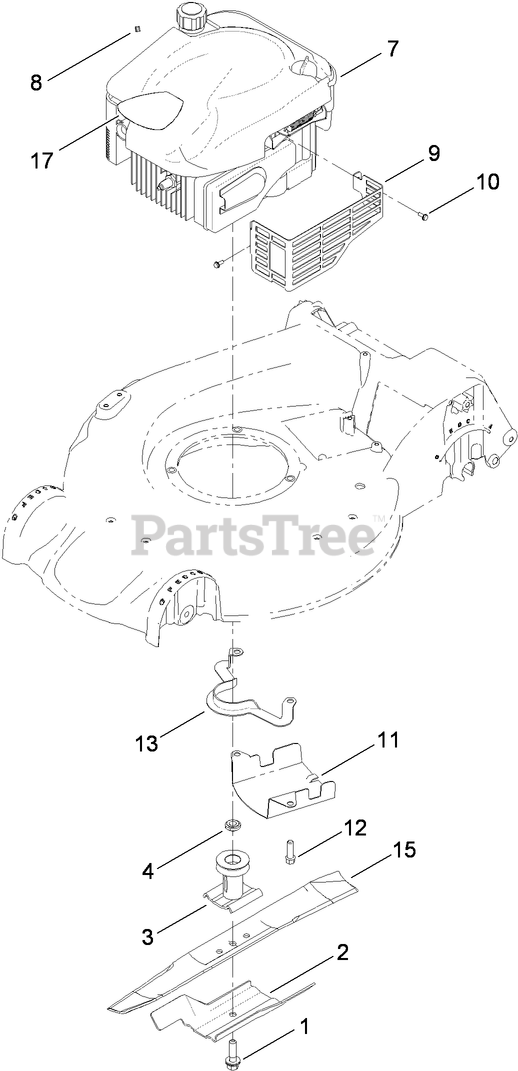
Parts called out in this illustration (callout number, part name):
2	ACCELERATOR-BLADE
3	DRIVER-BLADE
4	SPACER-DRIVER
8	STOP-ROPE
9	SHIELD-MUFFLER
10	SCREW-TAPTITE
11	SHIELD-GRASS
12	SCREW-TAPTITE
13	GUIDE-BELT
17	DECAL-SHROUD
